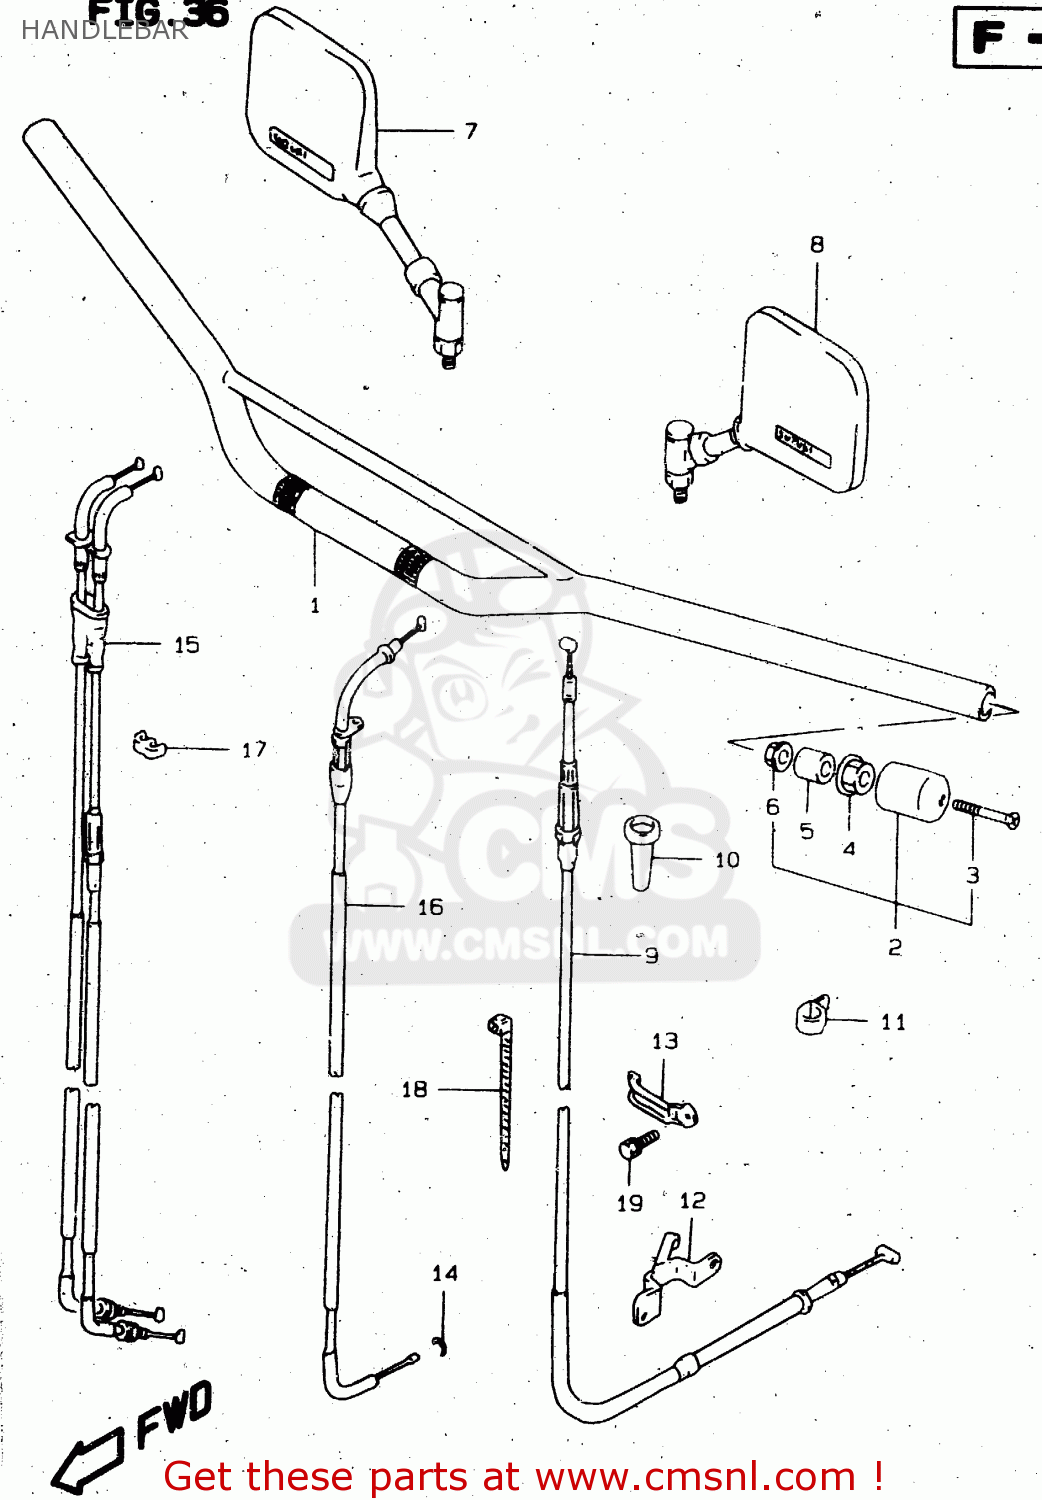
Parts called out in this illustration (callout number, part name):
1	HANDLEBAR(BLACK)
2	BALANCER SET,HANDLEBAR
3	SCREW
4	NUT
5	EXPANDER,HANDLE BALANCER
6	NUT
7	MIRROR ASSY,RR VIEW,R
8	MIRROR ASSY,RE
9	CABLE ASSY,CLUTCH
10	BOOT,CLUTCH CABLE
11	CLAMP
12	STOPPER,CLUTCH CABLE
13	CLAMP
14	E RING
15	CABLE ASSY,THROTTLE
16	CABLE,STARTER
17	CLIP
18	CLAMP(L:235)
19	BOLT
